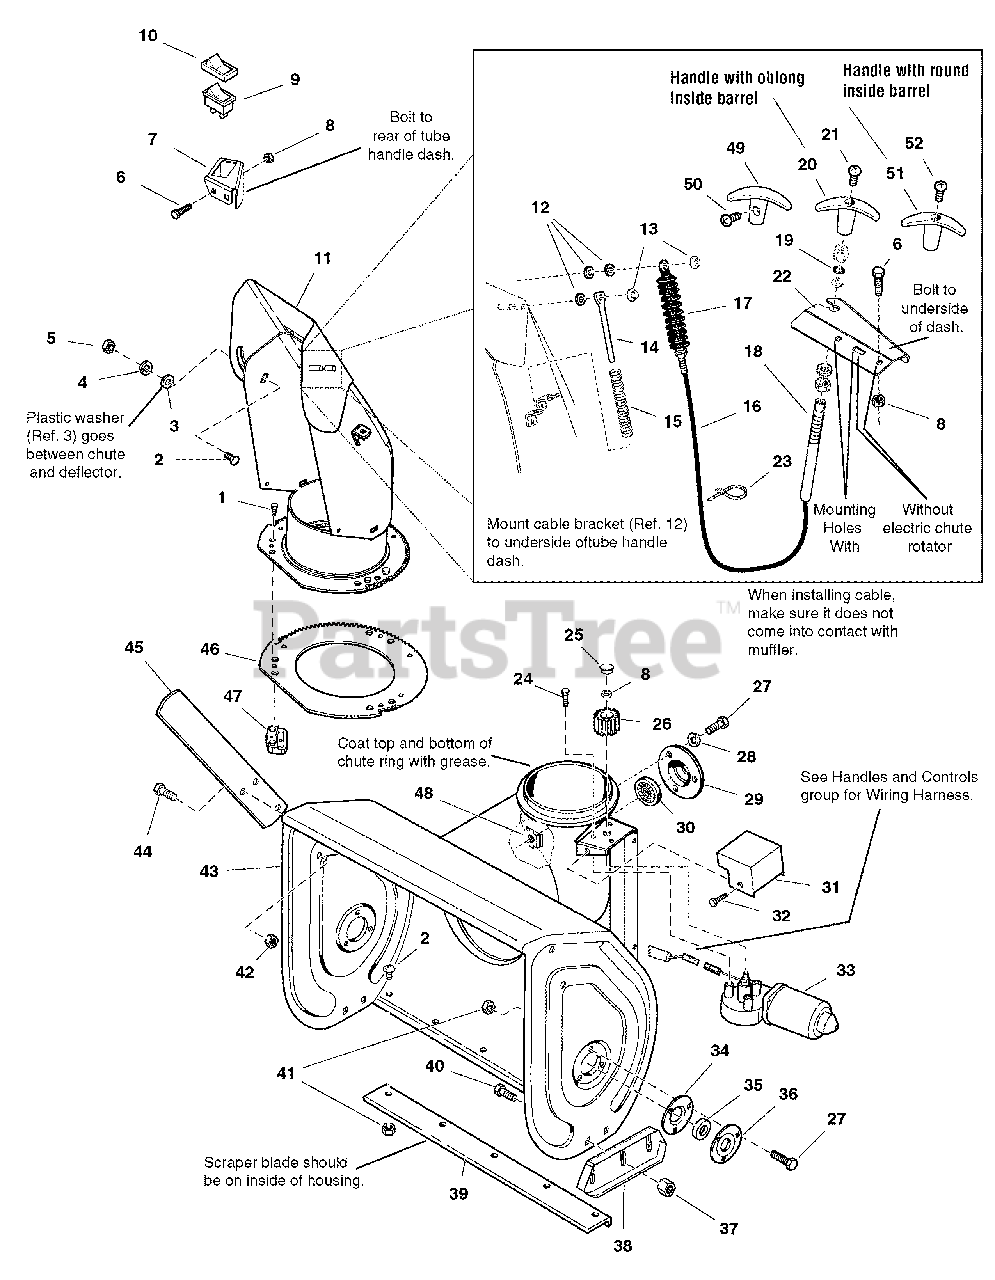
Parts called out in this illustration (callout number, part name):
1	SCREW, Hex Washer Head Pastite, 10-14 x 5/8
2	CARRIAGE BOLT, 5/16-18 x 3/4 G5
3	WASHER, Special, 97/250ID x 1-3/25OD x 3/100 Thick
4	WASHER, 5/16
5	NUT, Hex Lock ESNA Light, 5/16-18NC-3B
6	CAPSCREW, Hex Head 1/4-20 x 3/4 G5
7	SUPPORT, Switch 14GA
8	NUT, Hex KEPS, 1/4-20, Conical Washer
9	SWITCH, Rocker Chute
10	BOOT, Rocker Switch
11	CHUTE AND DEFLECTOR ASSEMBLY, Riveted, w/Pigtail
12	SPACER, Heat Treated
13	NUT, Push Pal, 1/4" Diameter Stud Capped
14	ROD, 5/16" Diameter, Spring Guide
15	SPRING, Complete
16	CABLE AND KNOB ASSEMBLY, Chute (Includes Ref. No. 17, 18, 19, 20 & 21)
17	BOOT, Bellows
18	COLLET
19	SEAL, Rod
20	KNOB
21	SCREW, 8-32
22	SUPPORT, Cable Tubular Handles, 12GA
23	TIE, Self Locking
24	SCREW, Conical Washer, 1/4-20 x 7/8 Dog Point
25	CAPLUG, For 3/4" Hole
26	PINION, 1-3/20 LG
27	CAPSCREW, Hex Head, 5/16-18 x 5/8 G5
28	LOCKWASHER, Spring, 5/16
29	RETAINER, Bearing
30	BEARING, Ball
31	COVER, Pinion, 18GA
32	CAPSCREW, Hex Washer Head Taptite, 1/4-20 x 1/2
33	MOTOR, Electric 60" Mower Rocky
34	FLANGE, Bearing, w/Fitting
35	BEARING, Cartridge
36	FLANGE, Bearing, 3/8" Deep
37	NUT, Hex Flange, 3/8-16 ESNA
38	SKID SHOE, 7GA Formed, Heat Treated
39	BLADE, Scraper, 35-3/4 for 38"
40	BOLT, Carriage, 3/8-16 x 1
41	NUT, Hex Flange, 5/16-18, Two-Way Lock GA
42	NUT, Hex Keps, 5/16-18, Conical Washer
43	HOUSING AND IMPELLER ASSEMBLY, 38"
44	CAPSCREW, Hex Head, 5/16-18 x 3/4 G5
45	CUTTER, Drift, 1/4" Thick, 20LG
46	HOLD DOWN, Chute
47	GEAR, Chute
48	NUT, Retainer Speed, 5/16-18
49	HANDLE "T"
50	SCREW, Set, Hex #10-24 x 3/8
51	HANDLE "T"
52	SCREW, Round Head
